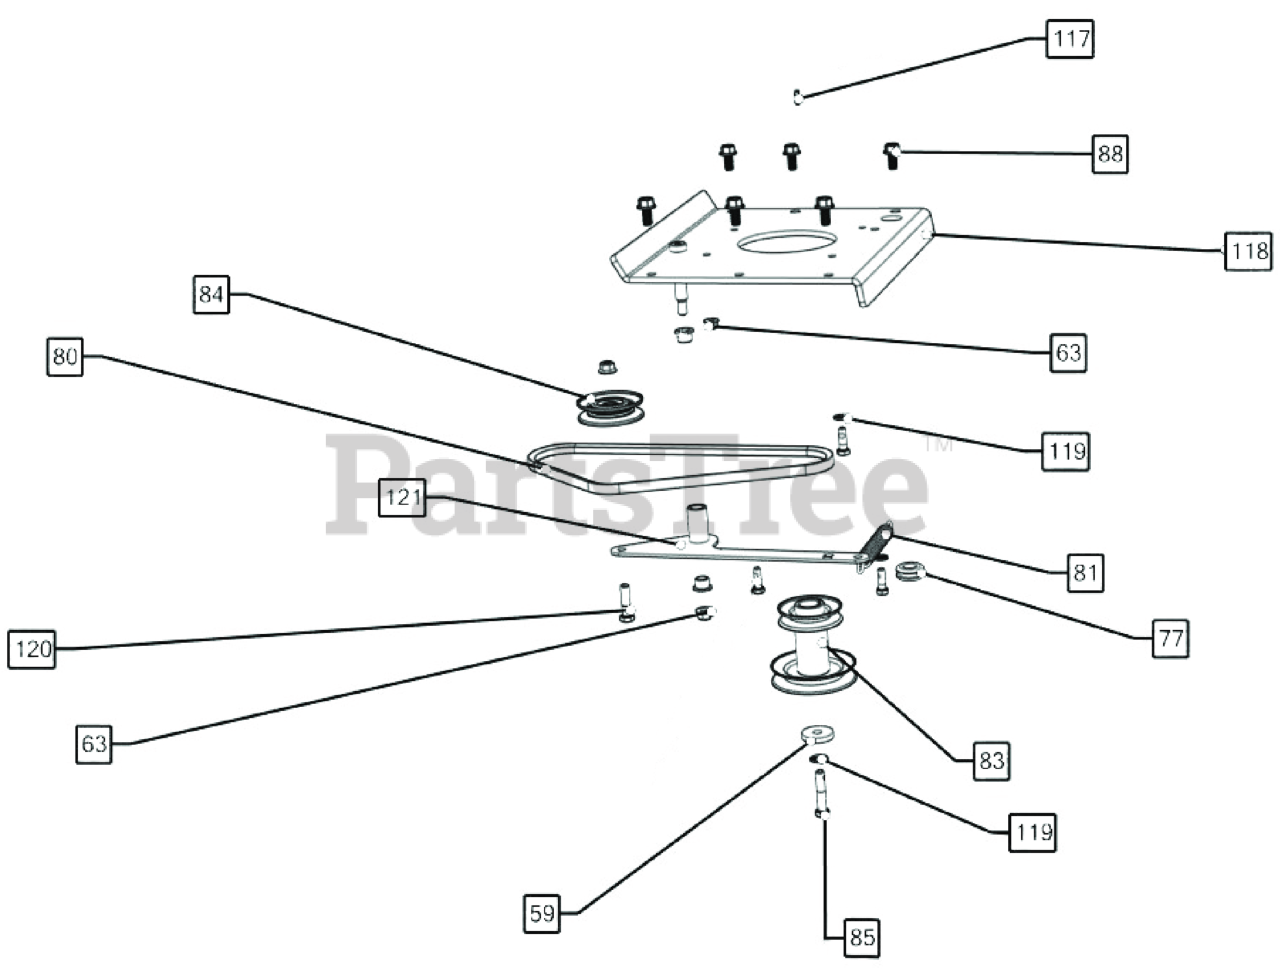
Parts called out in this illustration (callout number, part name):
59	WASHER 1.5 OD X .453 ID X .25 THK
63	NUT-HEX-NYLK, FLG .375"-16 ZP
77	GROMMET 0.69" I.D. FIT 1.00" HOLE
80	BELT V 4L X 34 OUTSIDE LG
81	SPRING IDLER BC
83	PULLEY, DOUBLE DRIVE
84	PULLEY 3V GROOVE IDLER
85	SCREWCAP 1/2-20 X 1 1/4 GR. 5 W/PATCH
88	SER HEX WASHER 3/8" - 16
117	KEY HI PRO 5/32" X 5/8"
118	PLATE, ENGINE MOUNT WA
119	WSHR-STL, BLV, .402 X .877 X .063 CN MZ
120	SCREWCAP 3/8" - 16 X 1/2" HCS ZP
121	KIT, SC181H TRANSMISSION PULLEY SERVICE
